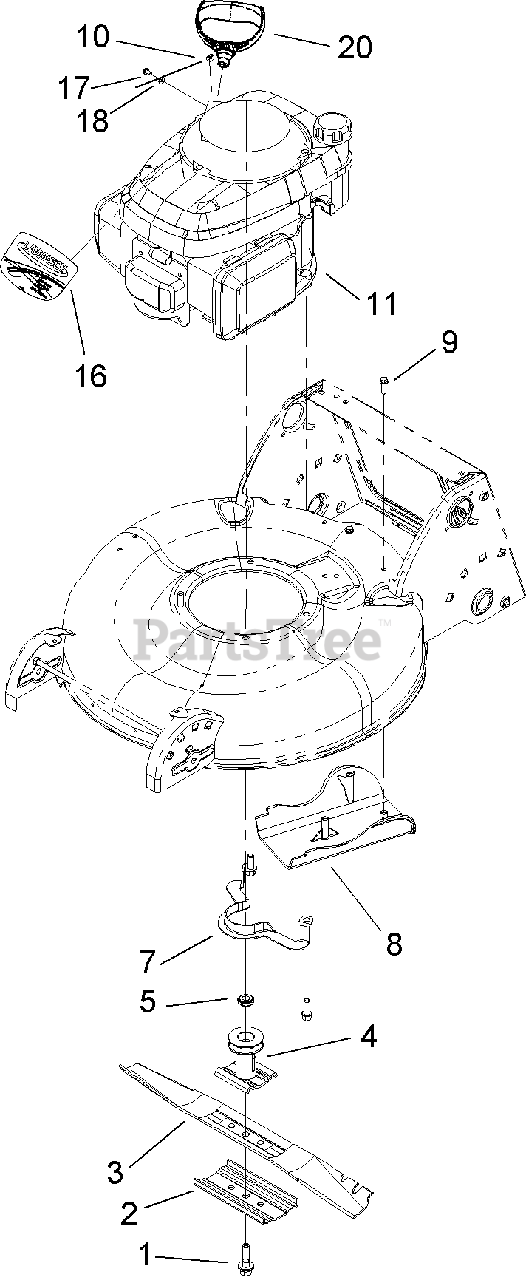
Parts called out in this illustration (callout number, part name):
1	BOLT-BLADE
2	SUPPORT-BLADE
3	BLADE-21 IN
4	BLADE DRIVER ASM
5	Spacer-Driver
8	COVER-BELT
9	SCREW-HWH
10	STOP-ROPE
17	SCREW-METRIC
18	WASHER-FLAT
20	HANDLE-RECOIL
